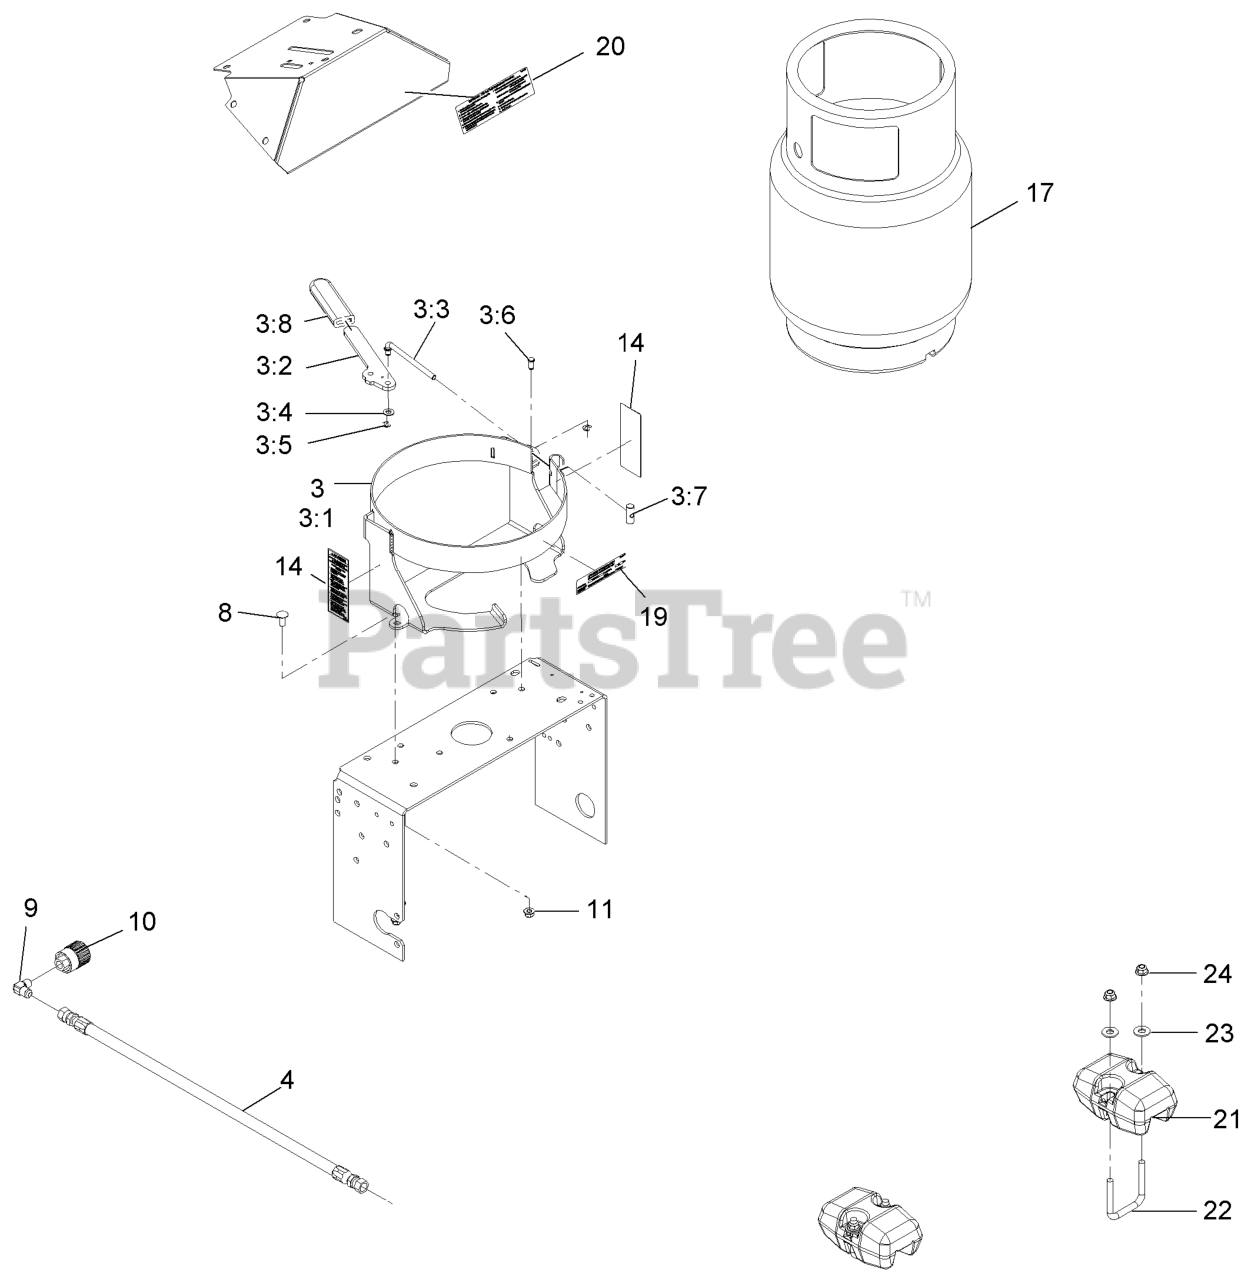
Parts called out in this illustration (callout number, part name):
3	ASM, LP TANK MOUNT
3:1	WELD, TANK MOUNT
3:2	ARM, LEVER
3:3	LINKAGE, LATCH
3:4	WASHER-PLAIN
3:5	E-RING,5/16 HEAVY DUTY
3:6	PIN-CLEVIS
3:7	TRUNNION, LATCH
3:8	GRIP-LEVER
4	ASM, HOSE-LPG
8	BOLT-CARR
9	ELBOW 90DEG,1/4 NPT X3/8
10	CONNECTOR-LPG TANK, LH TH
11	NUT-HF, NI
14	DECAL-LPG WARNING
19	DECAL,LPG TANK SPEC VERTI
20	DECAL-TANK REPLACEMENT
21	WEIGHT-SUPPORT, CASTER
23	WASHER-FLAT
24	NUT-HF, NI
